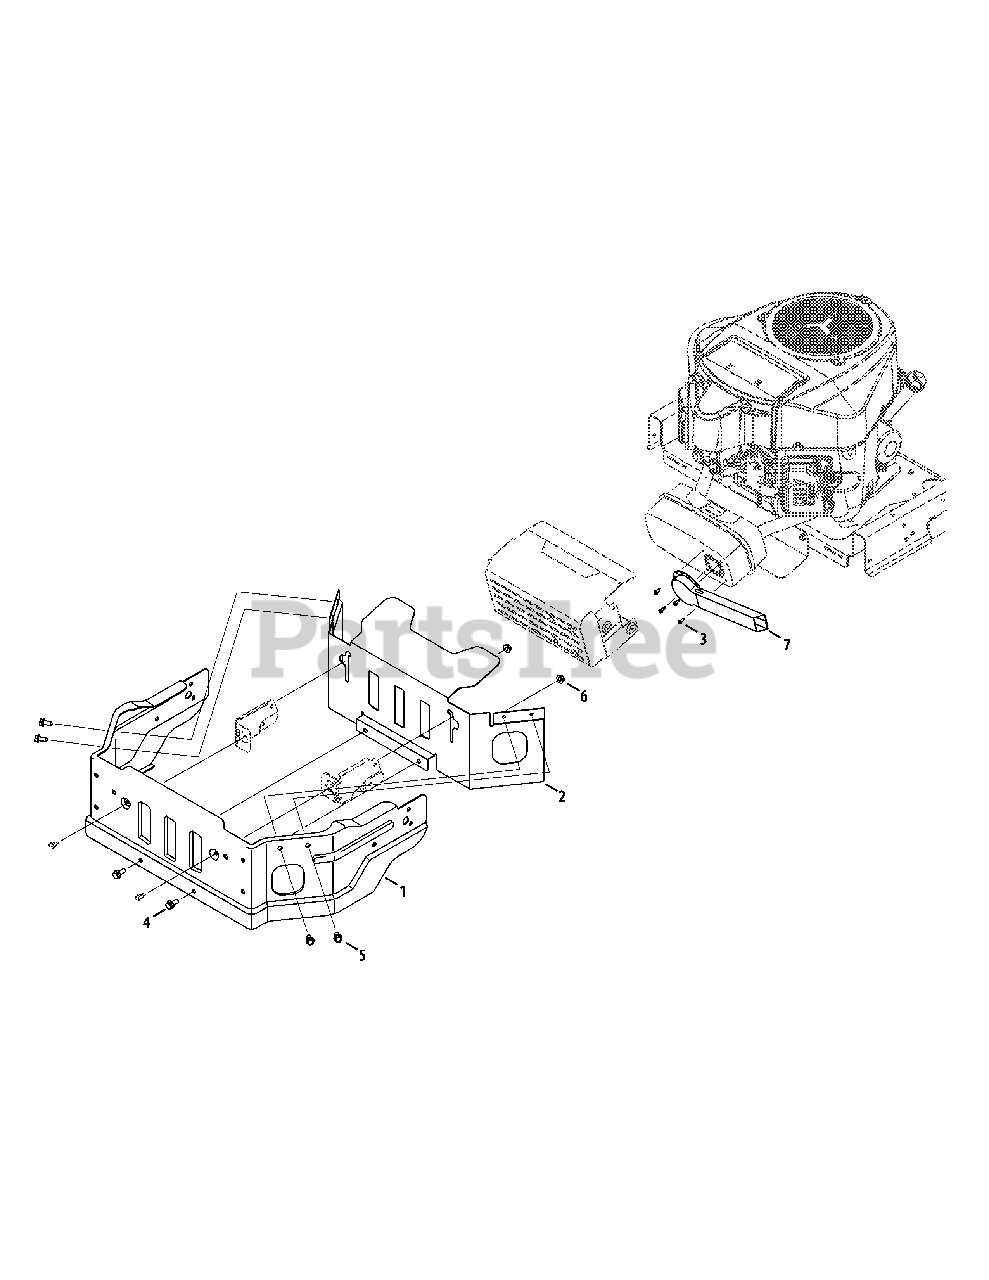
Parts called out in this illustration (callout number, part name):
1	Rear Bumper (Black)
1	Rear Bumper (Yellow)
2	Bumper Mount Muffler Sheild
3	#8 AB Screw, 18 x .500
4	Hex Flange Screw, 5/16-18
5	Tap Screw, 5/16-18 x .750
6	Flange Lock Nut, 5/16-18
7	Long Muffler Deflector
